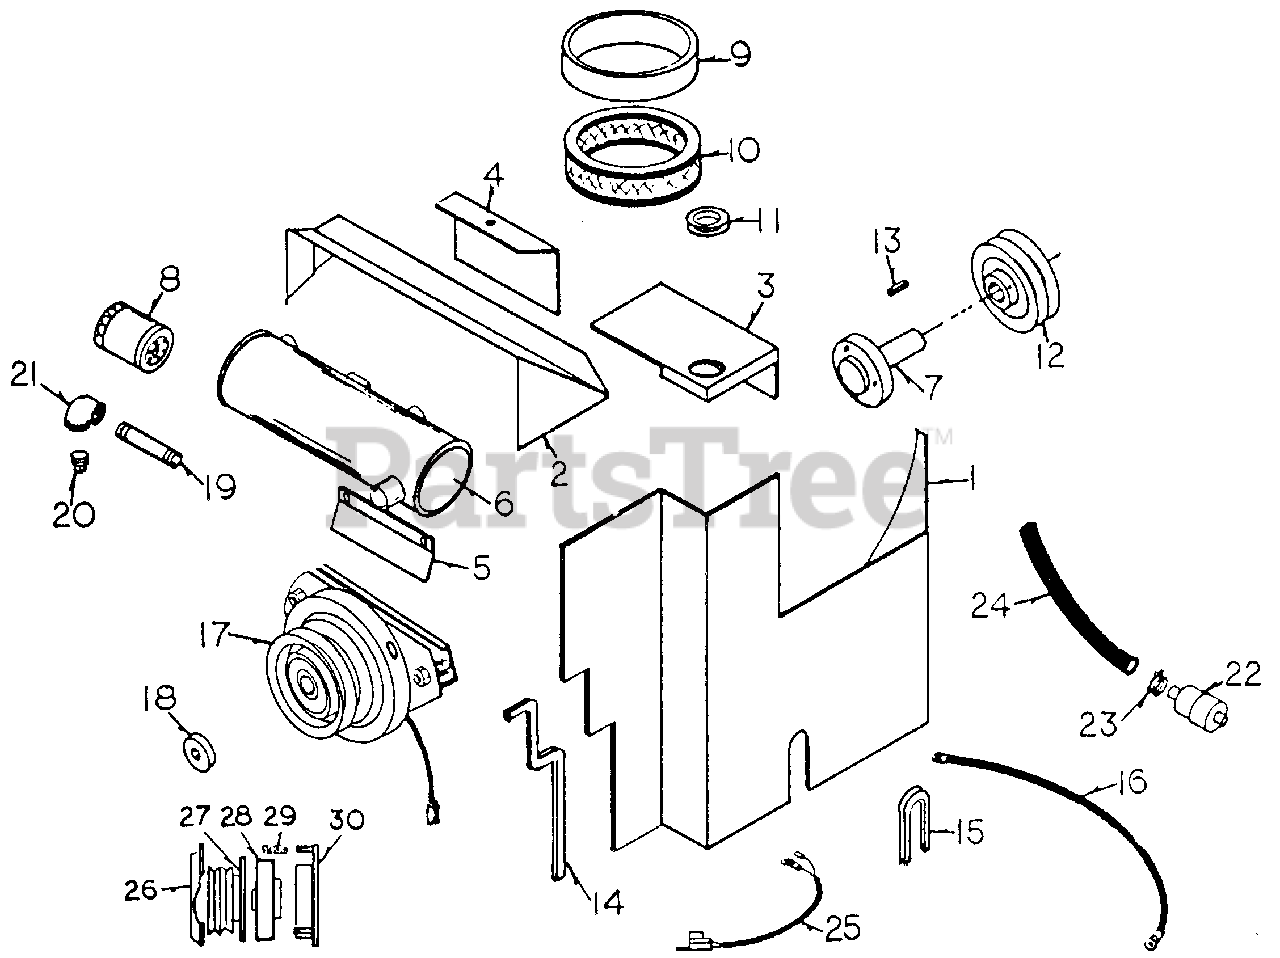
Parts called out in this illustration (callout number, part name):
1	Heat Shield, Psrt A
2	Heat Shleld, Part B
3	Heat Shield, Part C
4	Heat Shield, Part D
7	Onan Engine Shaft
8	Onan Oil Filter
9	Onan Filter Element
10	Onan Fllter Cartridge
13	Key Stock, 1/4" x 1"
17	Electrlc Clutch
18	Clutch Retainer Washer
19	Pipe Nipple, 3/8"
20	Pipe Plug, 3/8"
21	Pipe Elbow, 3/8"
22	Fuel Filter
23	Fuel Llne Clamp
24	Fuel Line, 38"
25	Starter Harness
27	Clutch Amature
29	Clutch Brake Spring
